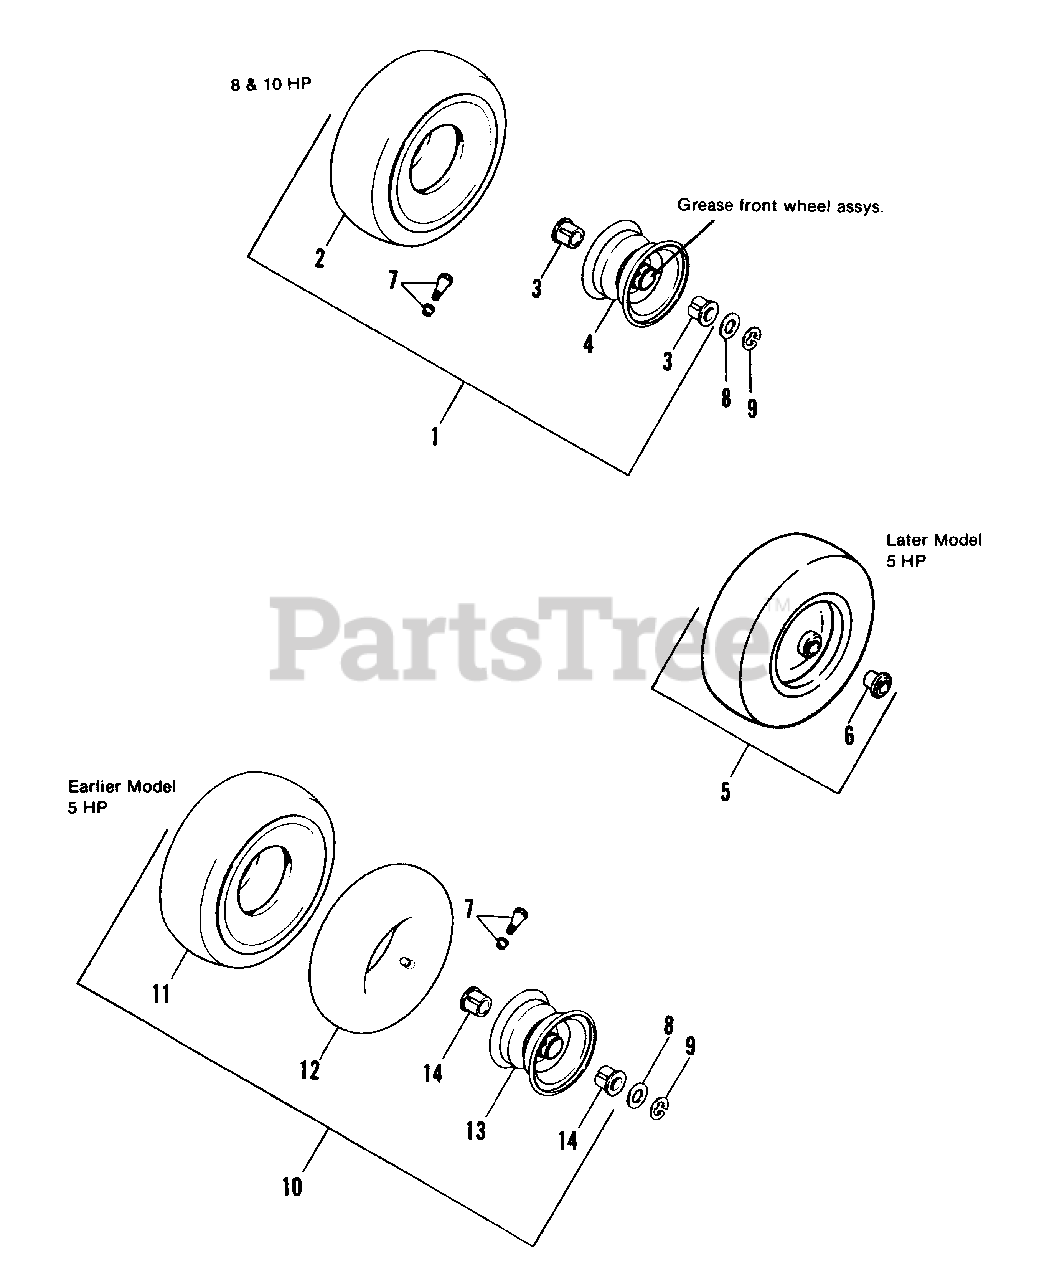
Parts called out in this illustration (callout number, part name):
1	FRONT WHEEL & TIRE ASSY., 4.10 x 3.50-4
3	BEARING, Valve
4	WHEEL ASSY.
5	FRONT WHEEL & TIRE ASSY. Semi-Pneumatic, 10-5 x 3.5
6	BEARING, Wheel
7	VALVE STEM & CAP
9	E-RING, Retaining, 3/4
10	FRONT WHEEL & TIRE ASSY., 4.10 x 3.50-4
11	TIRE, Turf
13	WHEEL ASSY.
14	BEARING
